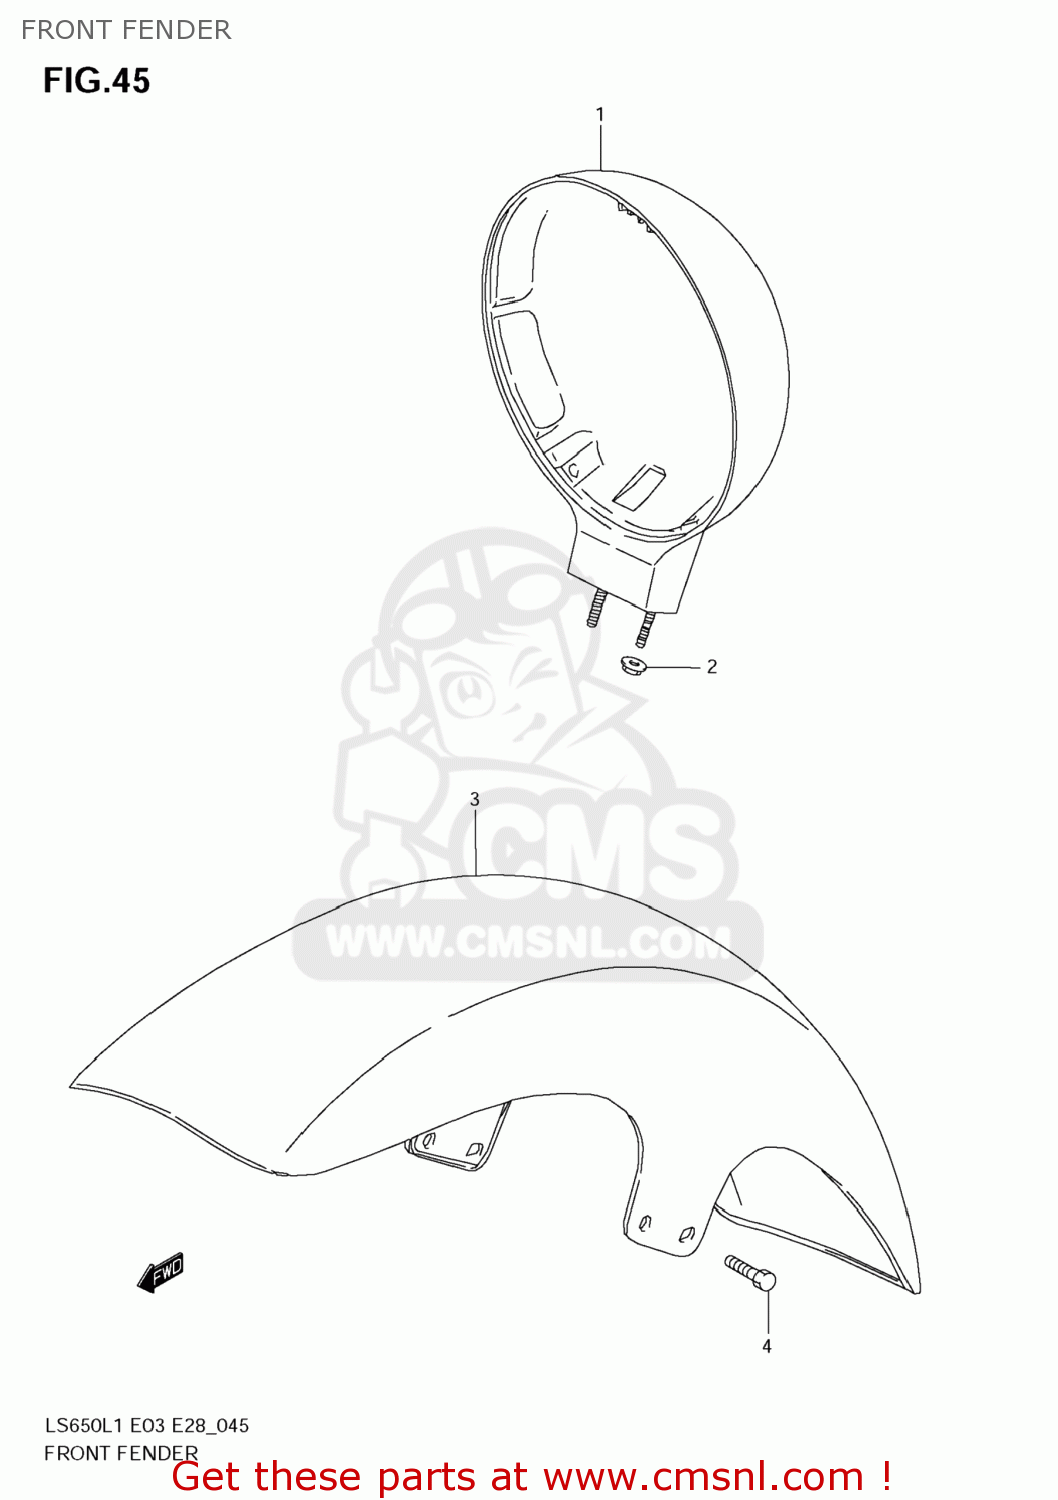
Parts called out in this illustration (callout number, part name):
1	HOUSING,HEADLAMP
2	NUT
3	FENDER,FR
4	BOLT
